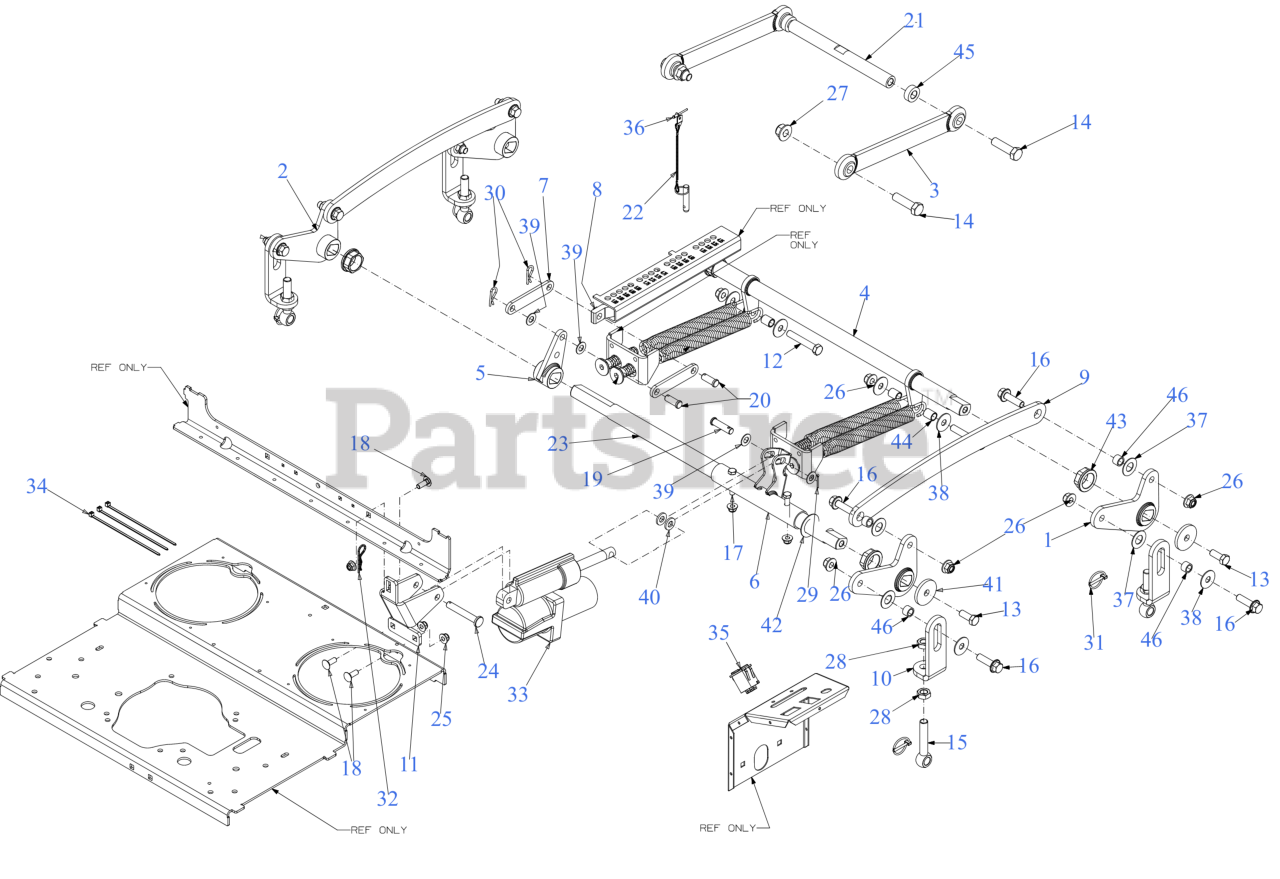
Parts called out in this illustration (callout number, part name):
4	FRONT DECK LIFT SHAFT
5	DECK LIFT HUB ASSEMBLY (LH)
6	LIFT BRACKET
7	DECK LIFT INDEX LINK
8	LIFT INDEX SLIDER ARM
11	LIFT CYLINDER BRACKET
12	SCREW-HEX 1/2-13 x 3.00
13	SCREW 1/2-13 x 1.25 GR5
14	SCREW 5/8-11 x 2.25 GR5
15	EYE BOLT 5/8-11 x 3.63
16	FLANGE BOLT 1/2-13:1.75:GR5
17	SCREW 3/8-16 x 2.0 GR5
18	CARRIAGE BOLT 3/8-16 x 1.00 GR5
19	CLEVIS PIN .500 x 1.875
20	CLEVIS PIN .500 x 1.25
21	FRONT LIFT SHAFT
22	DETENT PIN
23	LIFT SHAFT 1.25 DIA
24	CLEVIS PIN .50"OD
27	FLANGE LOCK NUT
29	COTTER PIN-1/8 D
30	COTTER PIN
31	LYNCH PIN .1875
32	COTTER PIN .125X2.
33	ELEC/HYD LIFT CYLINDER
34	7" CABLE TIE
35	DECK LIFT SWITCH
36	FULL TUBULAR RIVET
37	FLAT WASHER .760ID X1.49OD x .06
38	WASHER .51 x 1.5 x .07
39	FLAT WASHER .510 x .995
40	FLAT WASHER .510 x 1.000 x .125
41	FLAT WASHER .53"x2.125"x.25"
42	THRUST WASHER 1.25X1.94X.063 7000
43	FLANGE BEARING
44	SPACER 0.535 x 0.68 x 0.83
45	SPACER .635X1.25X.445
